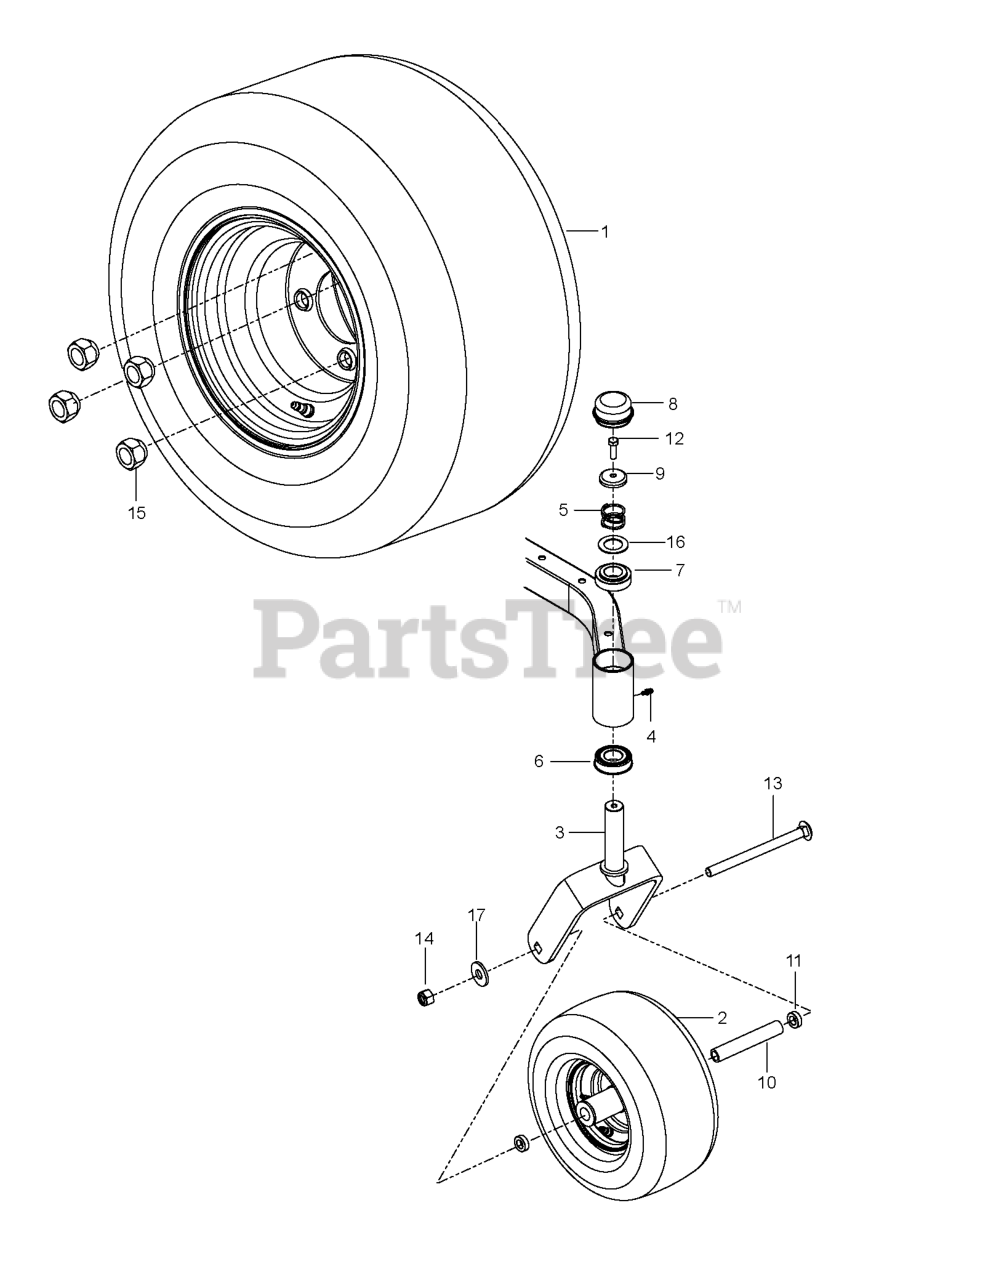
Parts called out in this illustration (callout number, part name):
1	TIRE.CASTER.ASSEM.11X4-5.GR
2	WHEEL.ASSEM.18X8.5-8.KENDA.ZTR
3	YOKE.CASTER.BLACK
4	ZERK, 3/16, DRIVE IN
5	SPRING, CASTER
6	BEARING FLANGED
7	BUSHING, CASTER
8	GREASE CAP
9	CASTER.PLUG
11	SPACER, 5/16"
12	5/16-18X1 HHB G5W/NY
13	RHSNB 1/2-13 X 6.50 GR2 ZD
14	NUT 1/2-13 HEX CNTRLK GR 5 ZD
15	LUG NUT 1/2F
16	WASHER, 1.025 ID X 1.64
17	WASH USS FLAT 1/2
